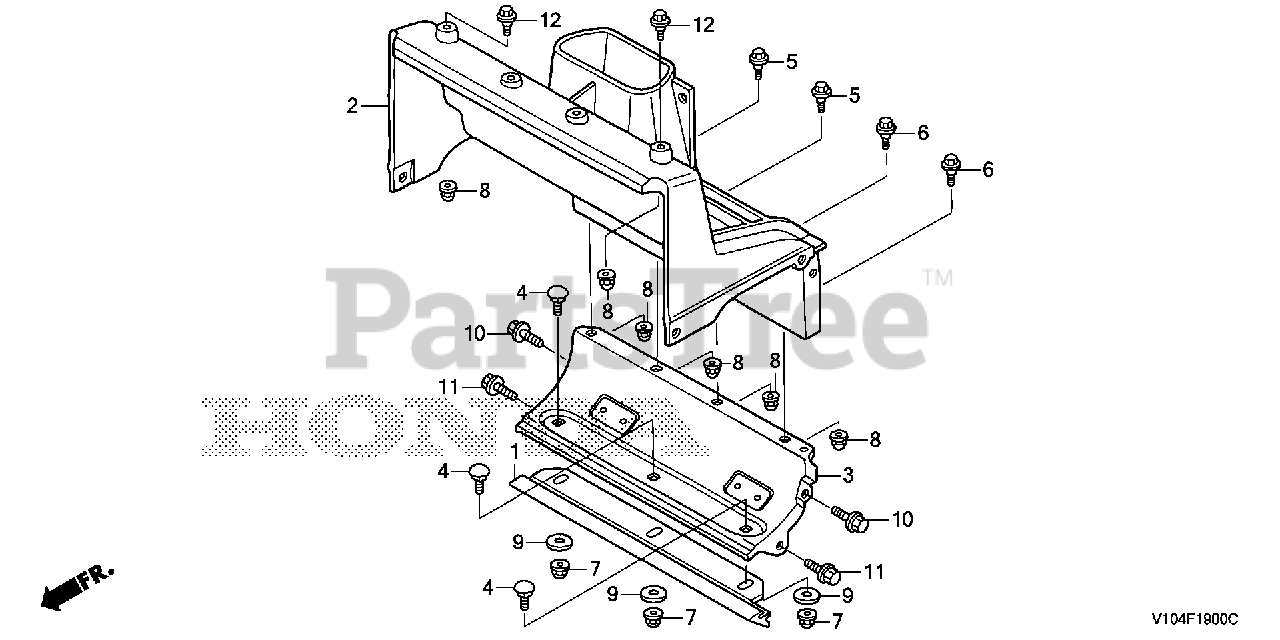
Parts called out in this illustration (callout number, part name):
1	BLADE, SCRAPER
2	HOUSING, AUGER
3	HOUSING, AUGER (LOWER)
4	BOLT, SPECIAL (8X20)
5	BOLT, TOP COVER
6	BOLT, CHUTE SETTING
7	NUT, FLANGE (M8X1.25) (SELF-LOCK)
8	NUT, SELF-LOCK (6MM)
9	WASHER (8.5MM)
10	BOLT, FLANGE (8X16)
11	BOLT, FLANGE (8X16)
12	BOLT, TOP COVER
